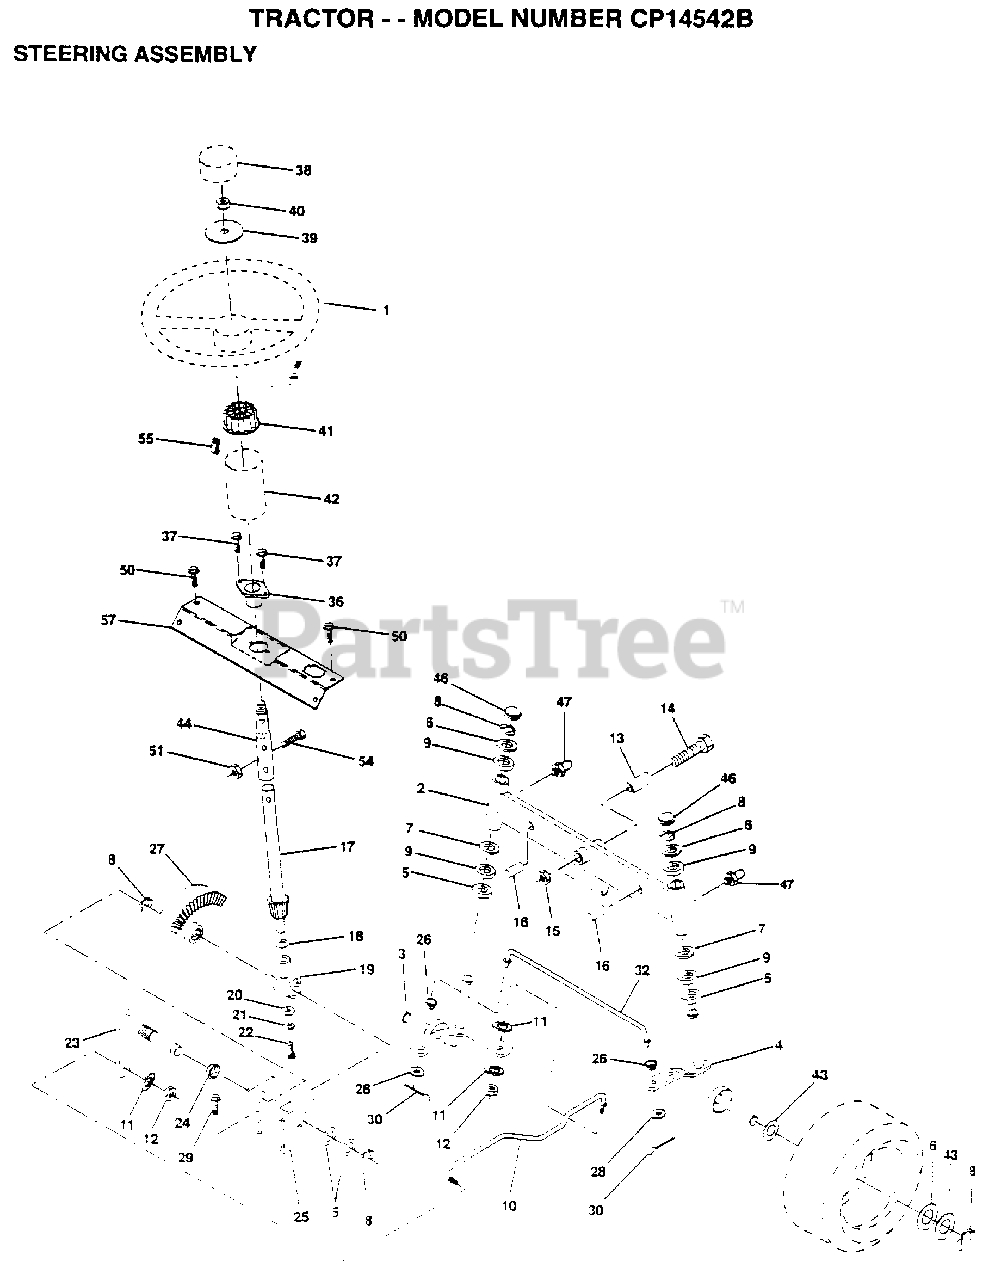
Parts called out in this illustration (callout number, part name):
2	AXLE ASM FRONT
3	SPINDLE LH
4	SPINDLE RH
5	WASHER .T
6	WASHER
7	WASHER
8	RING
9	COL. SRTG. BEAR.
11	LOCKWASHER
13	BEARING
14	BOLT HEX 5/8-11
15	"NUT-LOC,FLANGE LT"
16	AXLE PIN
17	SHAFT ASM STEERIN
18	THRUST WASHER
19	SUPPORT.SHAFT
21	LOCKWASHER
22	"SCREW,SPECIAL"
24	NYLINER T
25	"BRKT,STEERING"
26	BUSHING.DRAGLINK
27	GEAR SECTOR
28	WASHER
29	SCREW
30	COTTER PIN
32	TIE ROD
38	ST WHL INSERT CAP
39	WASHER T
40	GRIPCO NUT
41	ADAPTER-WHEEL LT
42	BOOT SHAFT STEER
43	WASHER
44	SHAFT EXT STEER
46	CAP
47	ZERK M
50	SCREW HEX CRT
51	NUT
54	BOLT
55	CLIP TINNERMAN
57	SUPPORT SHAFT STR
